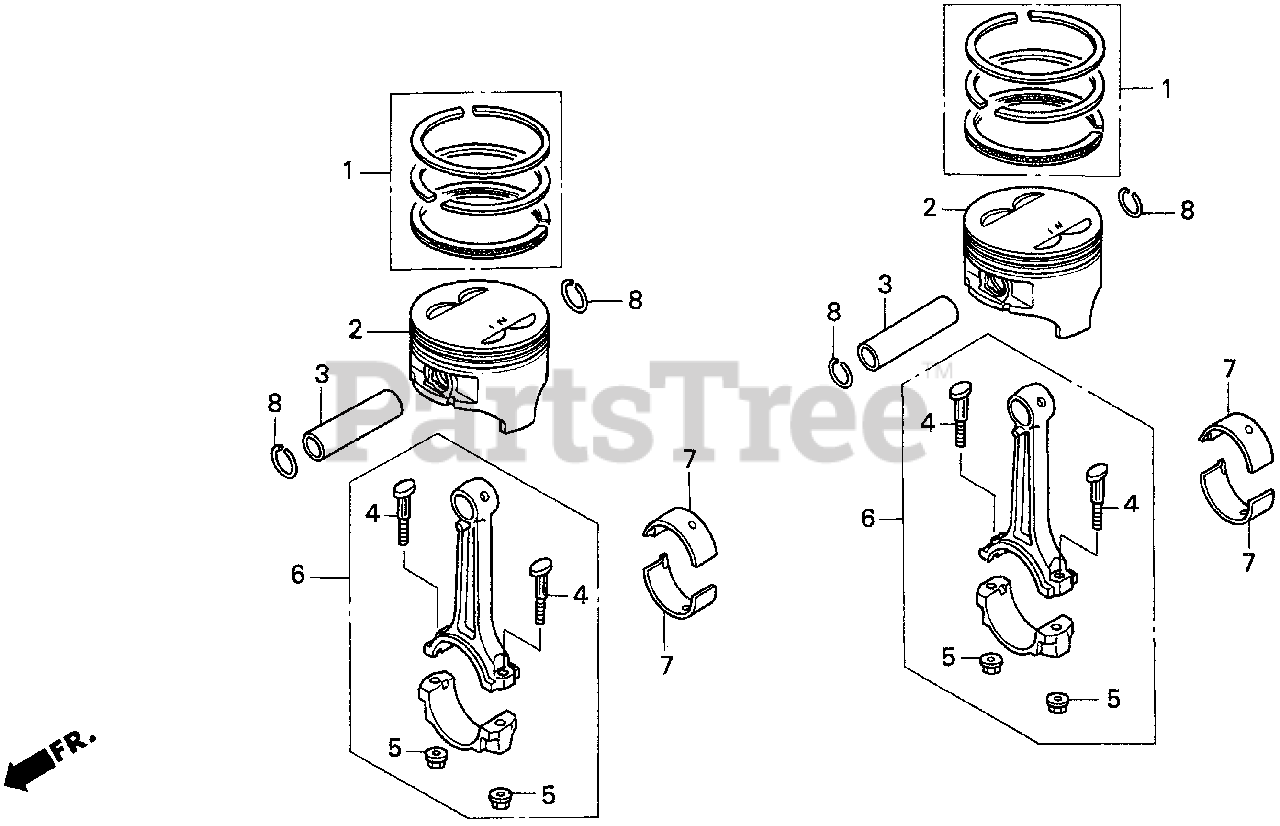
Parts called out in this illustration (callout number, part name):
1	RING SET, PISTON (STD)
1	RING SET, PISTON (OS 0.25)
1	RING SET, PISTON (OS 0.50)
2	PISTON (STD)
2	PISTON (OS 0.25)
2	PISTON (OS 0.50)
3	PIN, PISTON
4	BOLT, CONNECTING ROD (TOKAI TRW)
5	NUT, CONNECTING ROD
6	ROD ASSY., CONNECTING
7	BEARING A, CONNECTING ROD (BLUE)
7	BEARING B, CONNECTING ROD (BLACK)
7	BEARING C, CONNECTING ROD (BROWN)
7	BEARING D, CONNECTING ROD (GREEN)
7	BEARING E, CONNECTING ROD (YELLOW)
7	BEARING F, CONNECTING ROD (PINK)
7	BEARING G, CONNECTING ROD (RED)
8	CLIP, PISTON PIN (19MM)
